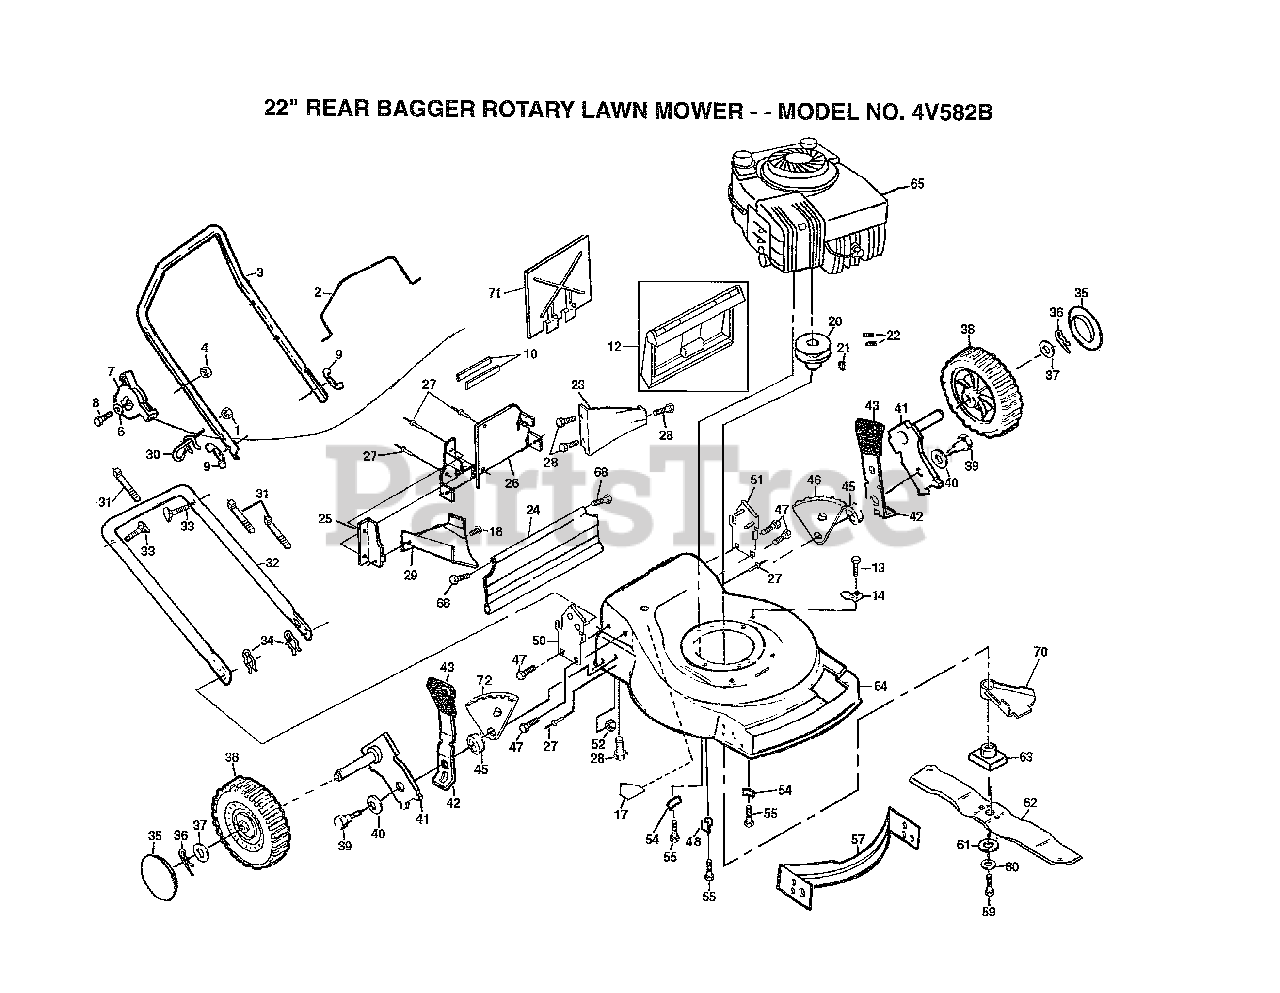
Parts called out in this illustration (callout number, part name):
1	NUT
2	BAIL.CONTROL.BLK.
3	"HANDLE,UPPER"
6	WASHER PM
7	CONTROL.THRT.45.6
8	SCREW.1/4-20X3.00
9	"NUT,WING PM"
10	"SEAL,REAR DOOR"
13	TAPPING SCREW
14	GUIDE CLIP PM
17	DECAL HYT
18	SCREW PM
20	ENGINE PULLEY PM
21	HI PRO KEY PM
22	SCREW
23	REAR BAFFLE
26	PLATE.BACK.22RD
27	BLIND RIVET
28	SCREW
29	DISCHARGE BAFFLE
30	ROPE GUIDE
33	BOLT.HANDLE.LM
34	HAIRPIN COTTER
35	HUB CAP
36	RETAINER CLIP PM
37	WASHER
40	"WASHER, BELLEVIL."
41	AXLE ARM
42	SPRING SELECTOR
43	KNOB PM
47	SCREW
48	DEBRIS SHLD RET
52	LOCKNUT PM
55	SCREW
59	SCREW
60	LOCKWASHER
61	"WASHER,HARDEN"
63	ADAPTOR.BLADE.LM
64	KIT.HSG.22RD.FWGD
68	HINGE SCREW
71	MULCHER PLATE
